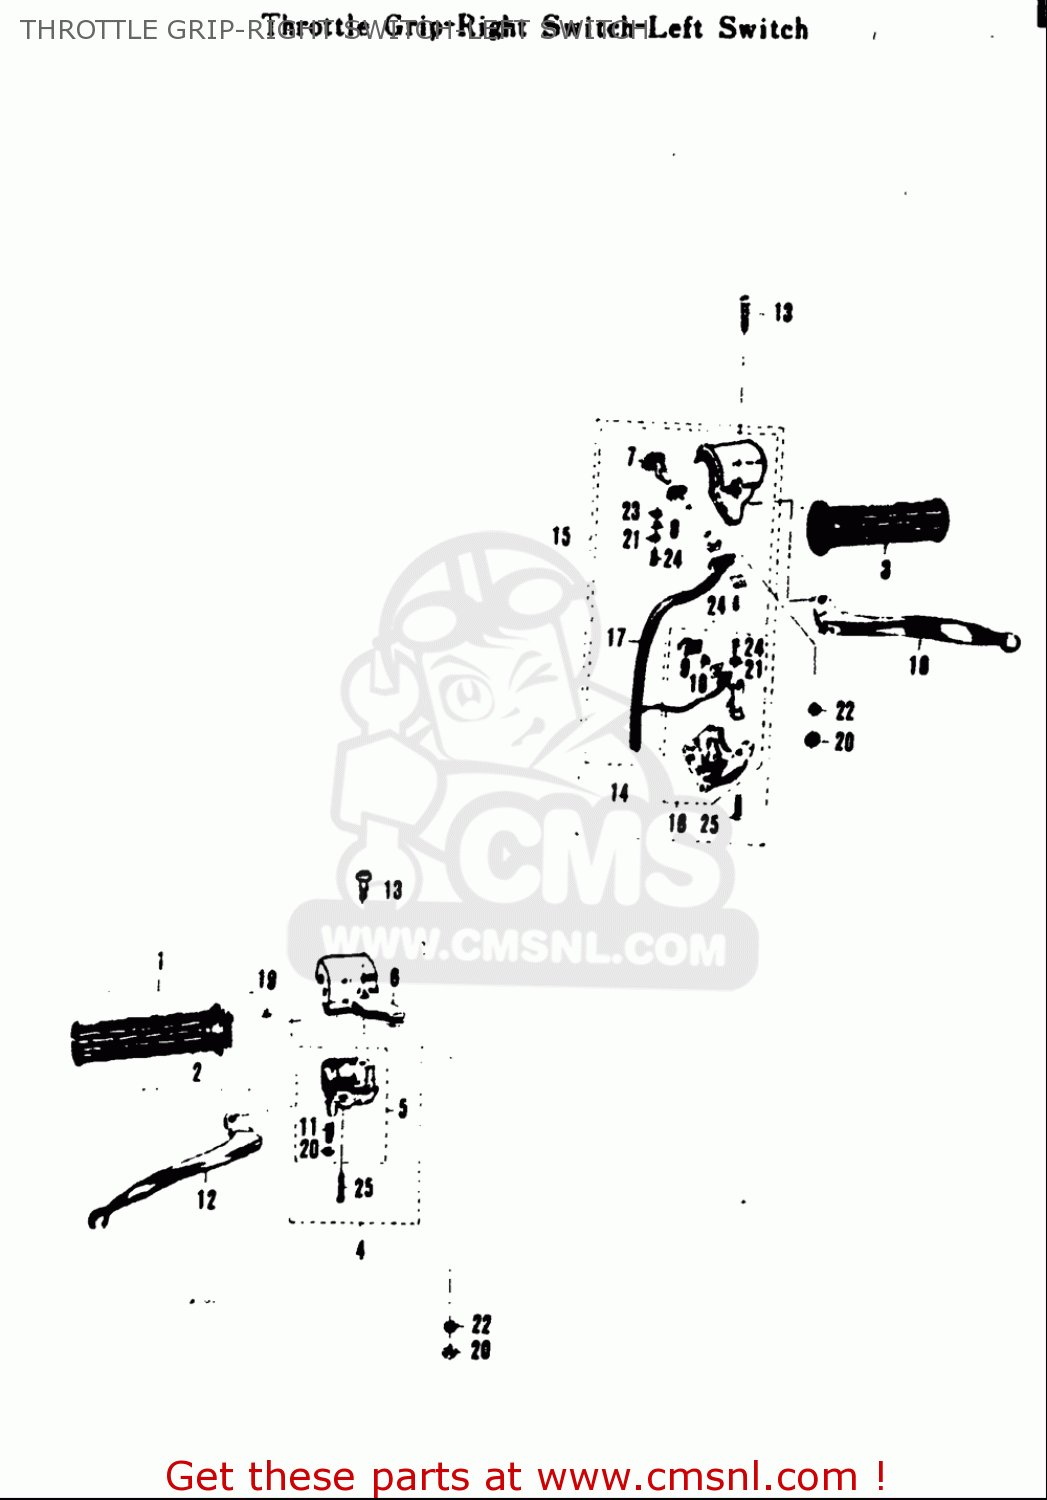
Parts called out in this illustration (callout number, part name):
1	GRIP,THROTTLE
9	BUTTON
10	SPRING
18	LEVER,CLUTCH
19	PIECE,THROTTLE END
20	NUT
21	WASHER,LOCK
22	WASHER,LOCK
23	WASHER
25	SCREW
